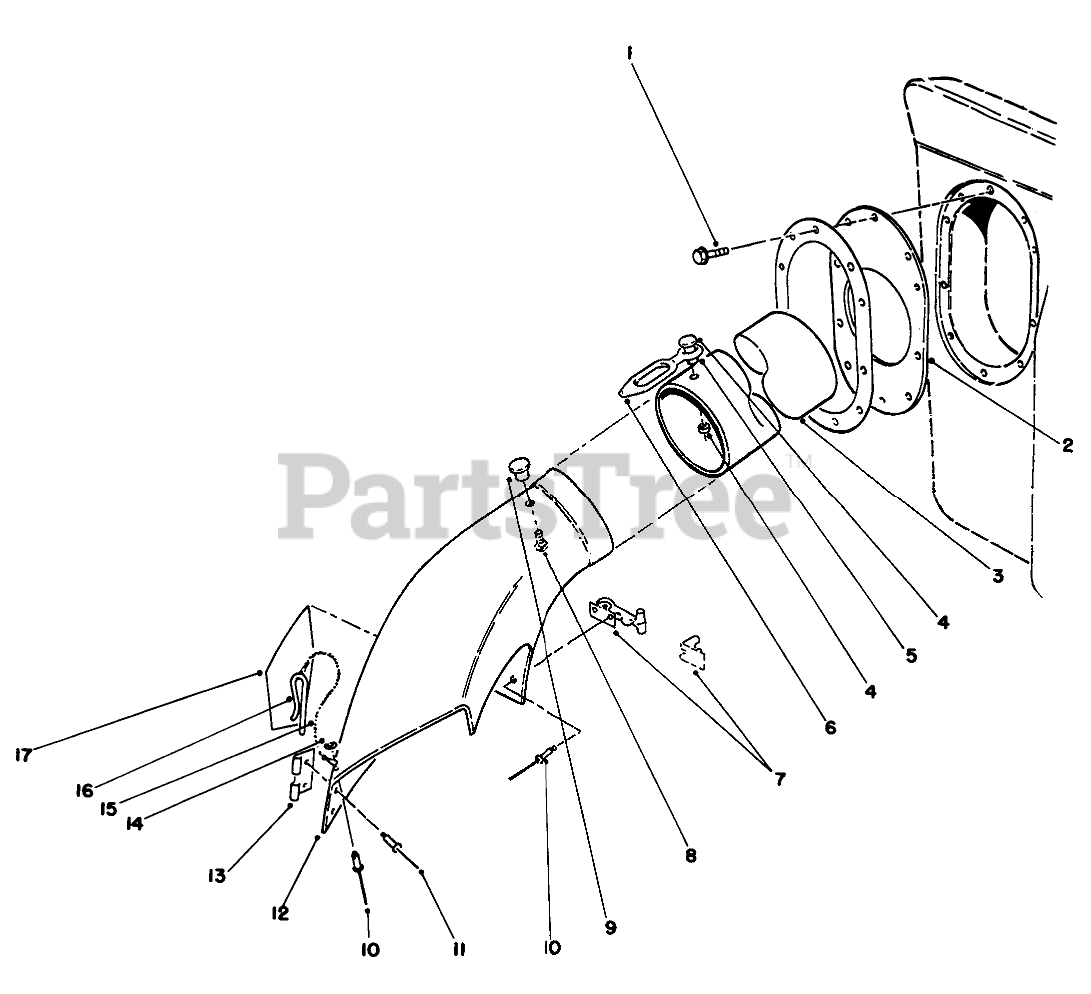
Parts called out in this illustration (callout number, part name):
1	Screw (Ref.)
2	RING-RETAINER, RUBBER
3	Duct-38"
4	FASTENER-PANEL
5	SPACER-INTERLOCK
6	RETAINER-DUCT
7	Latch-38"
8	SCREW-PPHTF
10	RIVET-POP
11	RIVET-BLIND
12	Elbow Assembly-38" (Incl. Ref. #7-17)
13	BRACKET-MOUNTING, CHUTE
14	WASHER-FLAT
15	LANYARD
16	PIN-LOCKING, CHUTE
17	DECAL-DANGER
